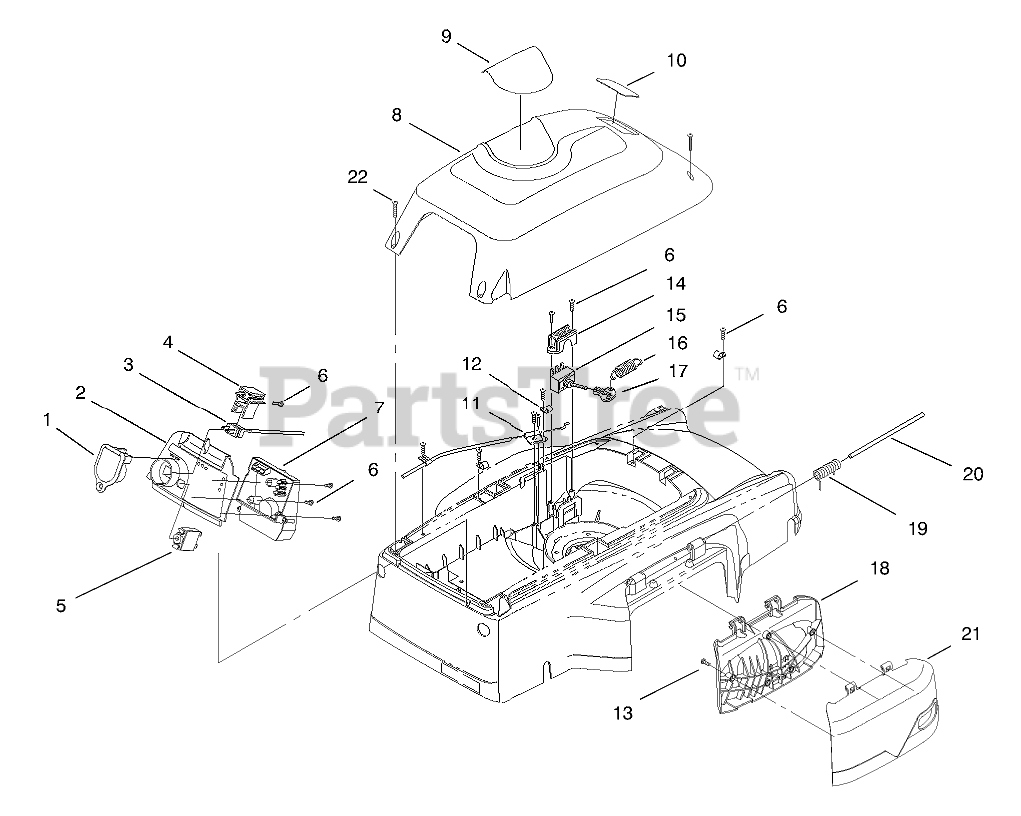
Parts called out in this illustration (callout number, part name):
2	ASM-Panel
3	PLUG ASM
4	HOUSING - PLUG
5	CIRCUIT BREAKER
6	SCREW-PPH
7	ASM - CIRCUIT BOARD 36V
8	ASM-Cover
9	DECAL - 36VOLT
10	PLATE-LOGO
11	BRACKET - CABLE
12	CLIP - WIRE
13	SCREW
14	CLAMP - SWITCH, TOGGLE
15	SWITCH - TOGGLE
16	SPRING - SWITCH
17	COVER LEVER-SWITCH
18	OBS MULCH PLUG - INSIDE
19	SPRING - TORSION
20	PIN - HINGE, MULCH PLUG
21	MULCH PLUG - OUTSIDE
22	SCREW-PPH
